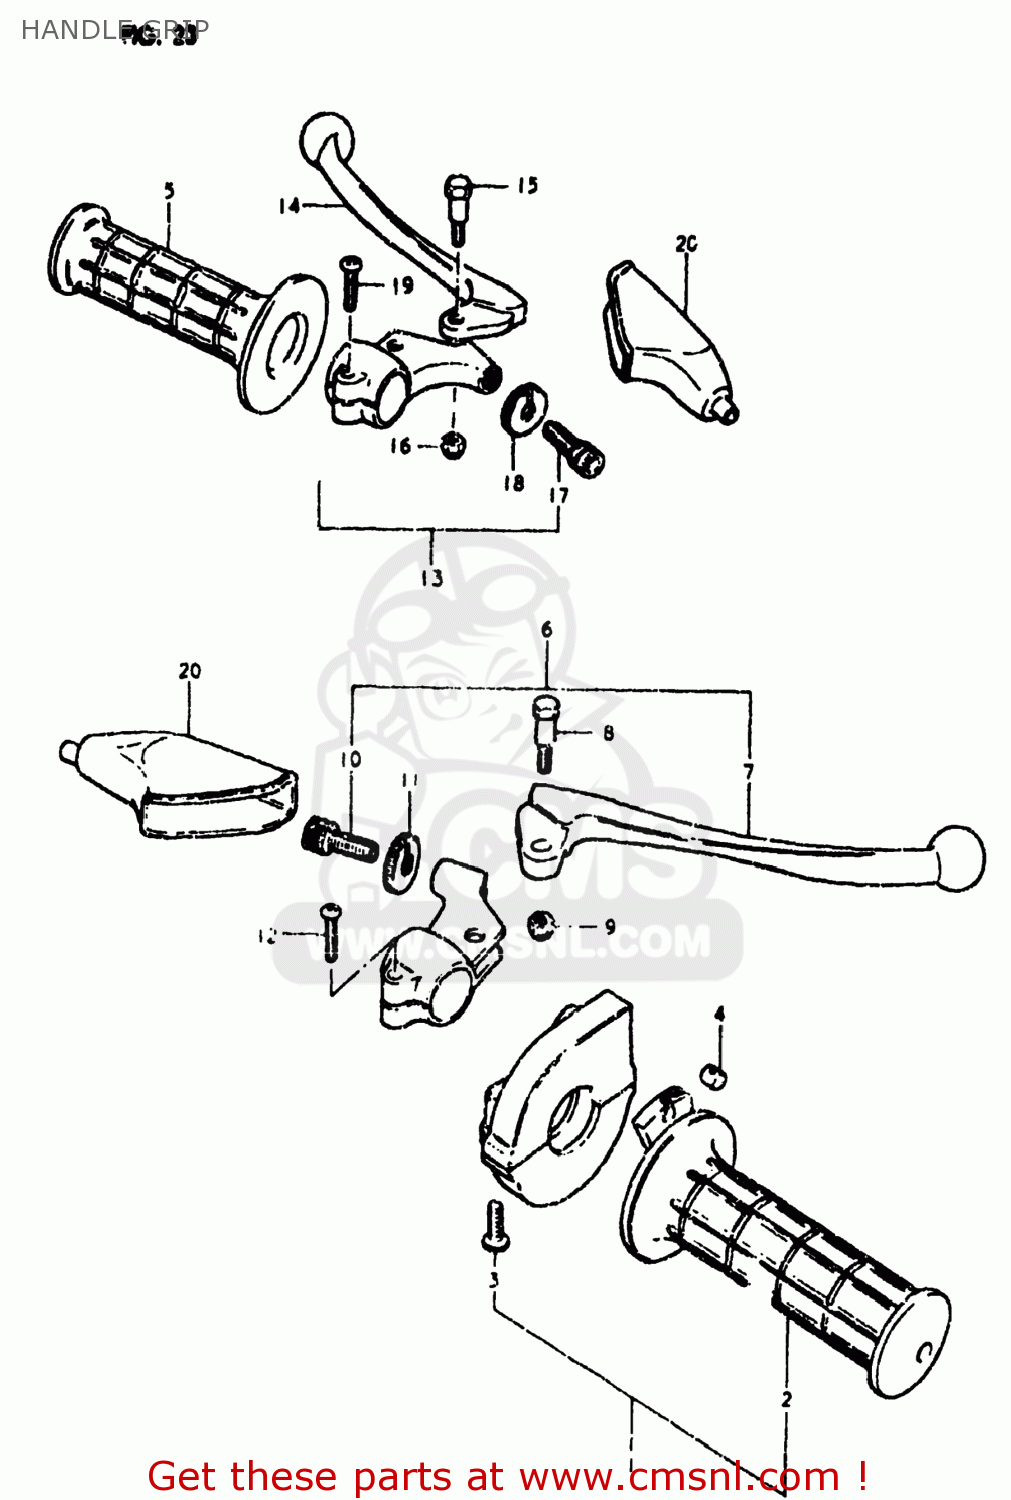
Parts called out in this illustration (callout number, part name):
1	CASE ASSEMBLY,THROTTLE
2	GRIP,THROTTLE
3	SCREW
4	PIECE,THROTTLE END
5	GRIP,LEFT
6	LEVER ASSY,BRAKE
7	LEVER,BRAKE
8	BOLT,LEVER
9	NUT 6MM
10	ADJUSTER,CABLE
11	NUT,CABLE ADJUSTER
12	SCREW
13	LEVER ASSY,CLUTCH
14	LEVER,CLUTCH
15	BOLT,LEVER
16	NUT 6MM
17	ADJUSTER,CABLE
18	NUT,CABLE ADJUSTER
19	SCREW
20	COVER,CLUTCH LEVER
